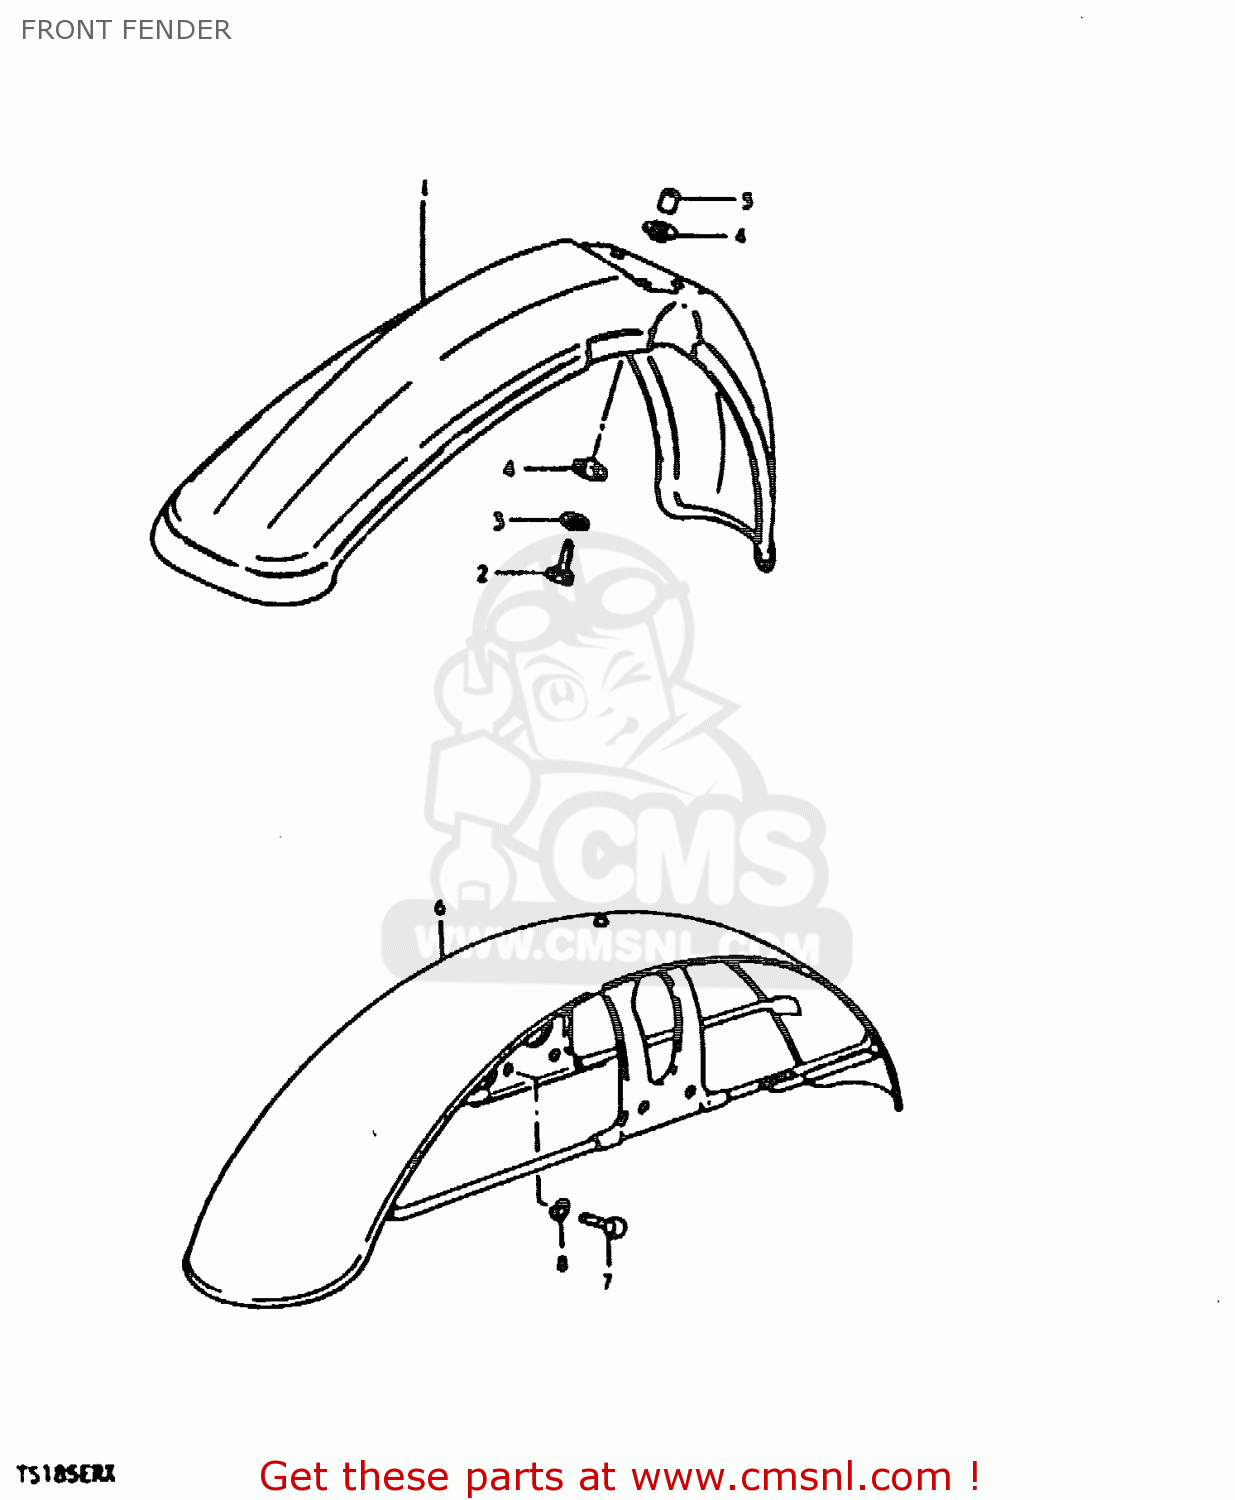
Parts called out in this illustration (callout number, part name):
1	FENDER,FR
2	BOLT
3	LOCK WASHER
4	SPACER
5	SPACER
